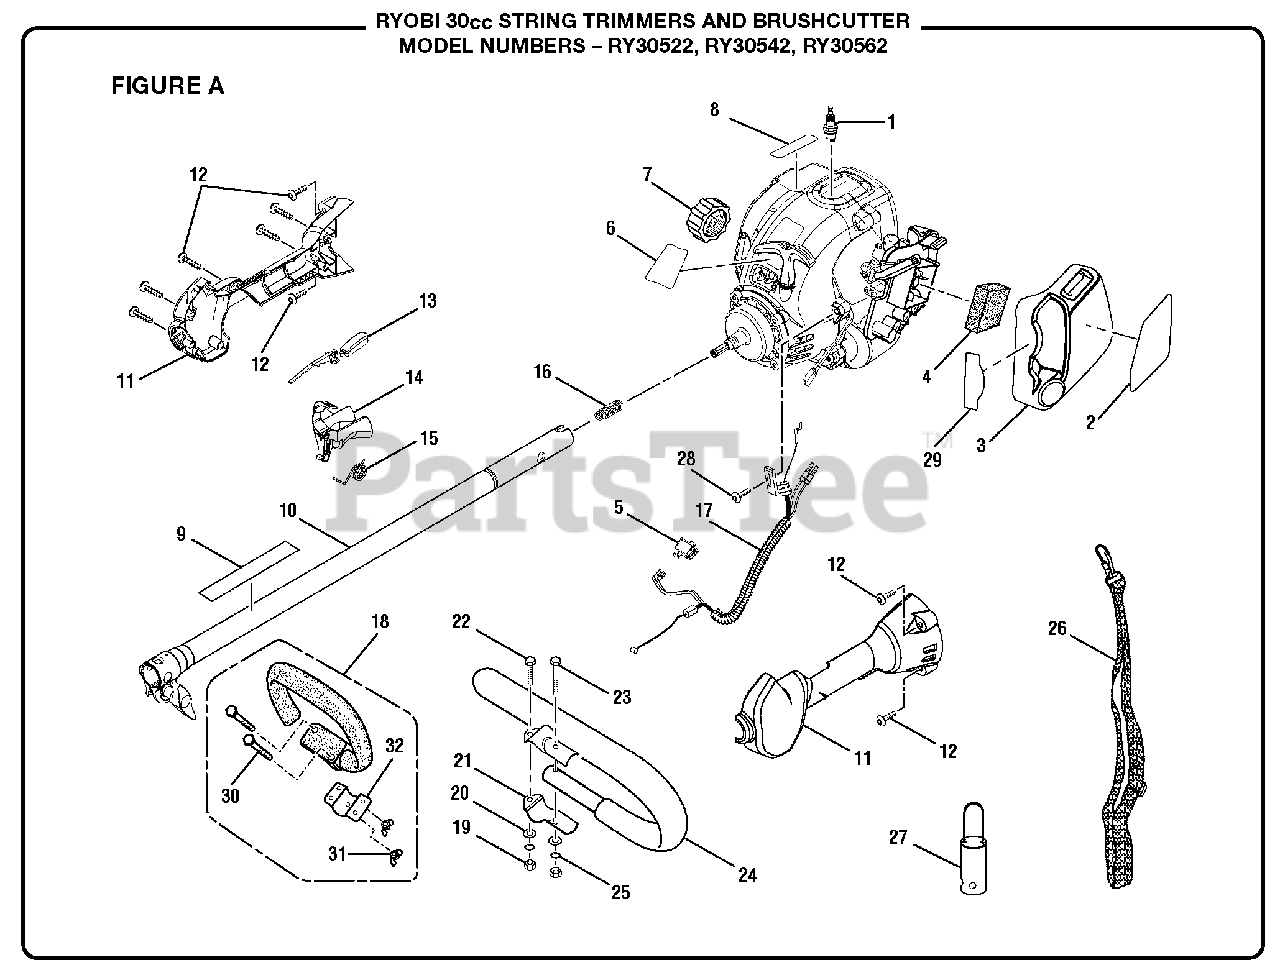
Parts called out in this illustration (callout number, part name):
1	Spark Plug
2	Starting Label
3	Air Box Cover
4	Air Filter Element
5	Switch (Momentary Contact)
6	Model Label (CS30)
7	Fuel Cap Assembly
8	Logo Plate
9	Warning Decal (CS30 and SS30)
10	Upper Boom Assembly (CS0 and SS30)
11	Control Handle Assembly
12	Screw (10-14 x 1 in.)
13	Trigger Lock
14	Trigger
15	Torsion Spring
16	Compression Spring
17	Throttle and Lead Assembly
18	Front Handle Assembly (CS0 and SS30)
19	Hex Nut (1/4-20) (BC30)
20	Washer (BC30)
21	Handle Bar Clamp (BC30)
22	Bolt (1/4-20 x 1 in.Hex Hd.) (BC30)
23	Bolt (1/4-20 x 1-1/2 in.Hex Hd.) (BC30)
24	"J" Handle and Grip (BC30)
25	Lock Washer (BC30)
26	Shoulder Strap (BC30)
27	Hanger Cap
28	Screw (10-24 x 7/8 in.)
29	Choke Label
30	Bolt (M5 x 30 mm Hex Hd.) (CS0 and SS30)
31	Wing Nut (M5)
32	Handle Bar Clamp (CS30 and SS30)
